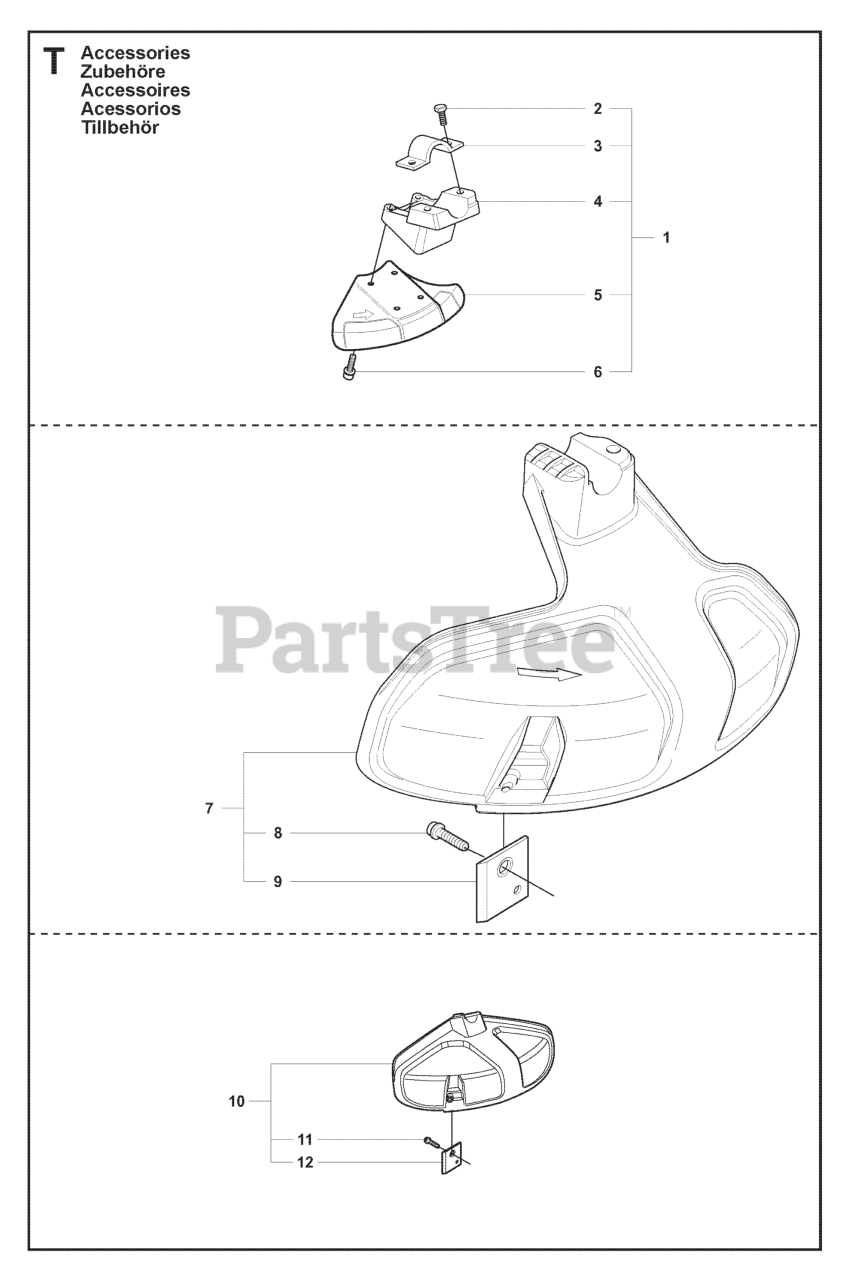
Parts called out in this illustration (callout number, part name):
1	TRIMMER GUARD ASSY
2	BOLT FLANGE - M6X20
3	CLAMP
5	BLADE GUARD
7	TRIMMER GUARD ASSEMBLY
9	LINE CUTTER
10	GRASS SHIELD
12	LINE CUTTER
